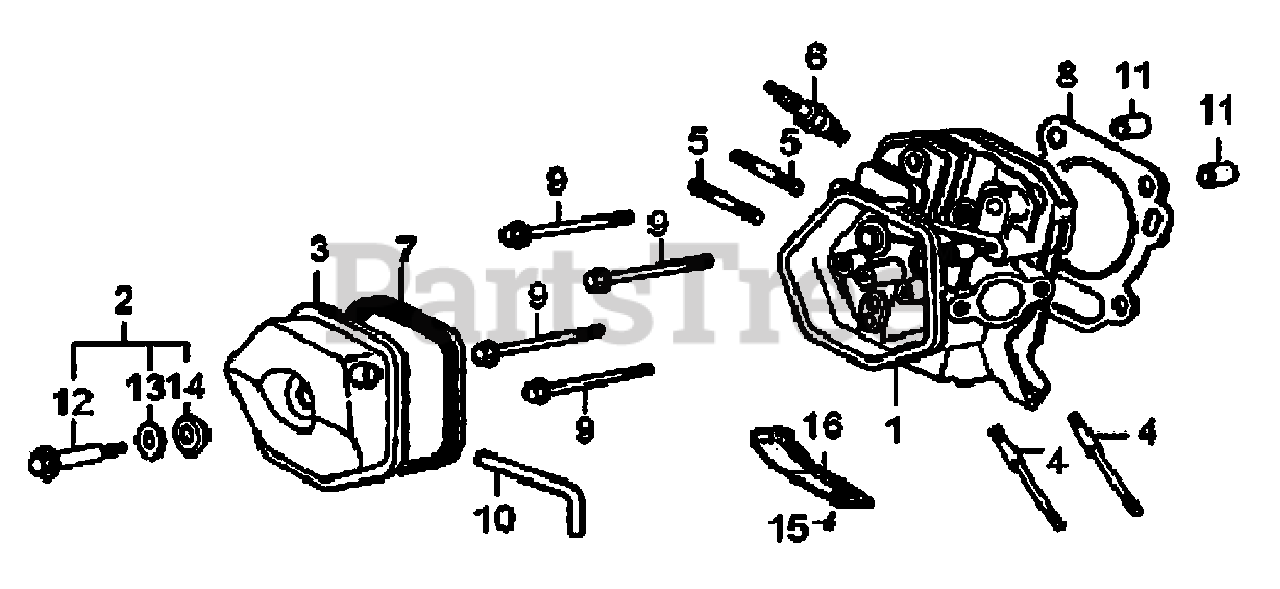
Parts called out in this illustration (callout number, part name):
1	HEAD, CYLINDER
2	BOLT, HEAD COVER, COMPLETE
3	COVER, HEAD
4	BOLT, STUD, INTAKE
5	BOLT, STUD, EXHAUST
6	PLUG, SPARK
7	GASKET, HEAD COVER
8	GASKET, CYLINDER HEAD
9	BOLT, FLANGED, CYLINDER HEAD
10	TUBE, BREATHER
11	PIN, DOWEL
12	BOLT, HEAD COVER
13	WASHER, HEAD COVER BOLT
14	O-RING, HEAD COVER BOLT
15	BOLT, SHROUD
